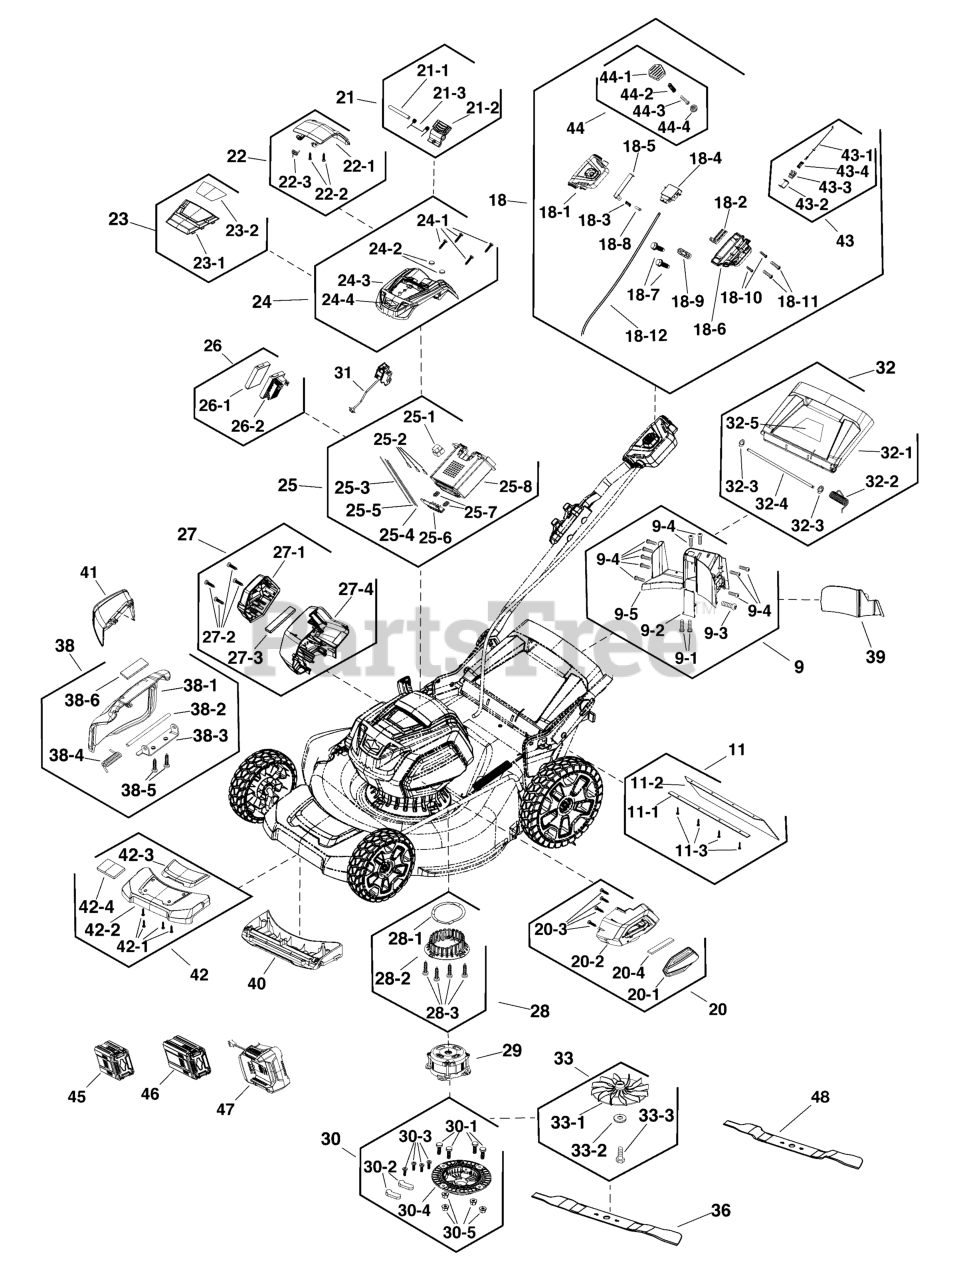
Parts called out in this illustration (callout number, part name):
9	KIT, Rear Baffle
9-2	COVER
9-5	BULKHEAD, Back
11	KIT, Rear Flap
11-1	BRACE
11-2	FLAP, Rear
18	KIT, Control Panel
18-1	TOP COVER
18-2	SLIDER
18-3	SPRING
18-5	PLATE
18-6	COVER, Bottom
18-8	PIN
18-9	CLAMP
18-12	WIRE
20	KIT, Cover, Left
20-1	HOUSING, Left
20-2	COVER, Left
20-4	SCREEN, Dust
21	KIT, Battery Release
21-1	PIN
21-2	BUTTON
21-3	SPRING
22	KIT, Battery Cover
22-1	COVER, Battery
22-3	SPRING
23	KIT, Cover
23-1	COVER
23-2	SHROUD
24	KIT, Top Cover
24-2	MAGNET
24-3	COVER, Top
24-4	B&S LOGO
25	KIT, Battery Box
25-1	CONNECTOR
25-2	CONTACT
25-3	WIRE, Yellow
25-4	WIRE, Red
25-5	WIRE, Black
25-6	TERMINAL
25-7	SPRING
25-8	HOUSING, Battery
26	KIT, PCB
26-1	COVER, PCB
26-2	PCB
27	KIT, Cover, Right
27-1	COVER, Right
27-3	SCREEN, Dust
27-4	COVER, Right
28	KIT, Base
28-1	SEAL
28-2	BASE
29	KIT, Motor
30	KIT, Base, Motor
30-1	BOLT
30-2	DISC, Tension
30-4	BASE
30-5	NUT
31	KIT, Inverted Switch
32	KIT, Rear Cover
32-1	COVER, Rear
32-2	SPRING
32-3	WASHER, Split
32-4	SHAFT
32-5	LABEL
33	KIT, Fan
33-1	FAN
33-2	WASHER
36	KIT, Blade
38	KIT, Cover
38-1	COVER
38-2	SHAFT
38-3	BRACKET
38-4	SPRING, Torsion
38-5	SPRING, Torsion
38-6	DECAL, Side Discharge
39	KIT, Mulch Plug
40	KIT, Front Bulkhead
41	KIT, Deflector, Side Discharge
42	KIT, Front Panel
42-2	PANEL
42-3	COVER, Panel
42-4	DECAL
43	KIT, Cable
43-1	CABLE, Bail
43-2	SLIDER
43-3	SEAT
43-4	SPRING
44	KIT, Button, Start
44-1	BUTTON, Start
44-2	SPRING
44-4	COVER
45	* BATTERY, 2.0, 82V NA
46	* BATTERY, 4.0, 82V NA
47	* CHARGER, Battery, NA
48	BLADE, Mulching, 21"
